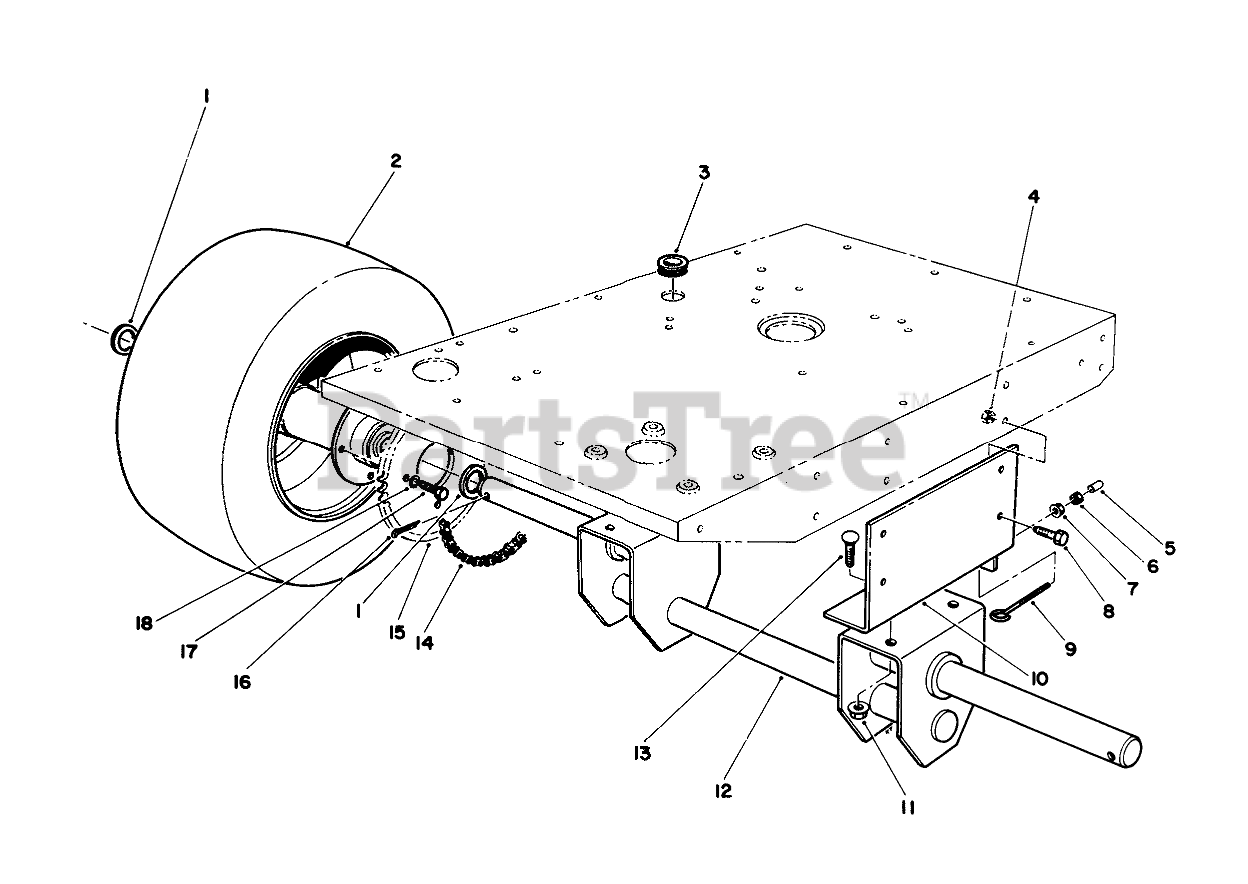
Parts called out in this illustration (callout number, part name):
1	WASHER-WHEEL
2	Tire & Wheel Assy-Rear
3	GROMMET
4	NUT-LOCK, NI
5	VINYL ROD TIP
6	NUT-HEX
7	NUT-HF
8	SCREW-HH
9	SCREW-ADJUSTING
10	LH REAR AXLE BRACKET
11	NUT-HF
12	REAR AXLE WA R
13	BOLT-CARR
14	CHAIN
15	DRIVE SPROCKET R
16	PIN-COTTER
17	SCREW-HH
18	WASHER-LOCK
